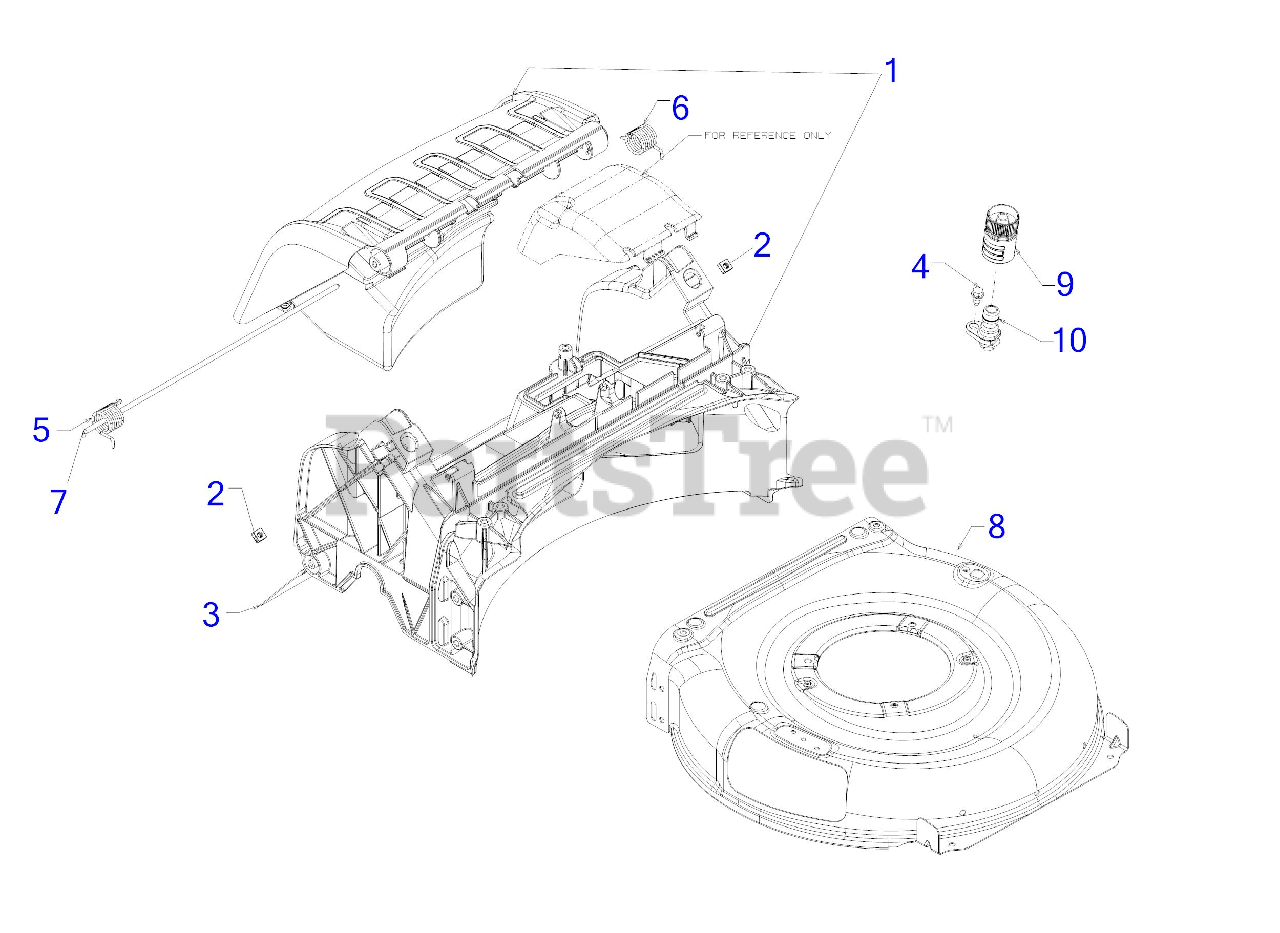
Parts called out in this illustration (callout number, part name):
1	REAR BAG BAFFLE ASSEMBLY
2	SQUARE NUT 1/4-20
3	TRAILSHIELD
4	SHOULDER SCREW 1/4-20 x .50
5	TORSION SPRING (RH)
6	TORSION SPRING (LH)
7	REAR DOOR PIVOT ROD
8	21" DECK (3N1)
9	WATER NOZZLE
10	DECK WASH NOZZLE
